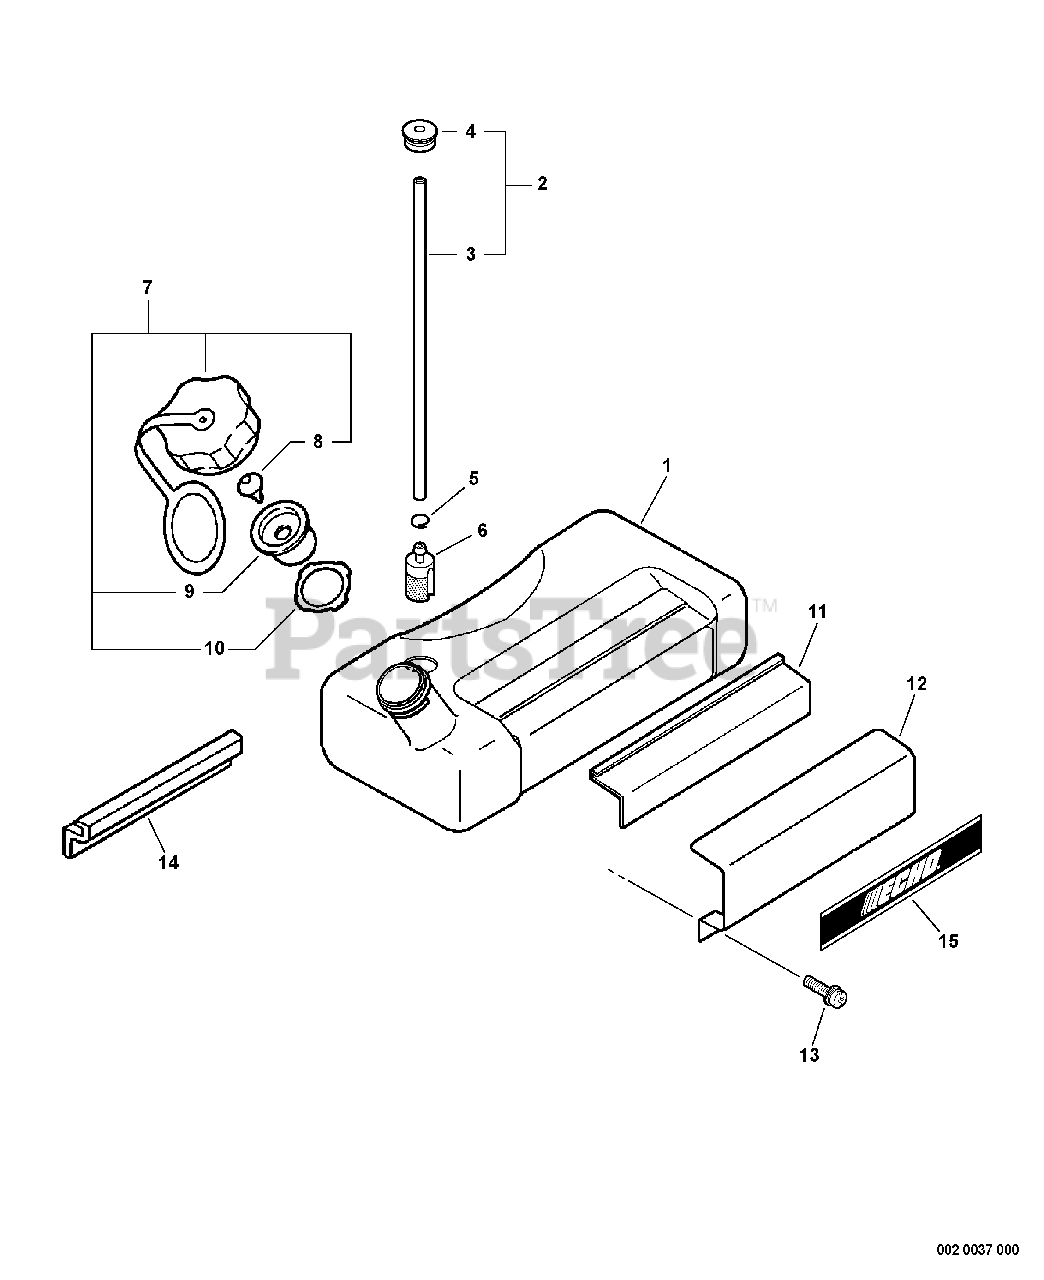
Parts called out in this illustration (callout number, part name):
1	TANK, FUEL
2	PIPE, FUEL - SPIRAL
3	PIPE, FUEL - SPIRAL
5	CLIP - 6
6	FILTER, FUEL
7	CAP ASSY
9	VENT HOLDER ASSY
10	GASKET, CAP
11	CUSHION, FUEL TANK
12	BRACKET, FUEL TANK
13	SCREW - 5X10
14	SEAT, FUEL TANK
15	LABEL - ECHO
